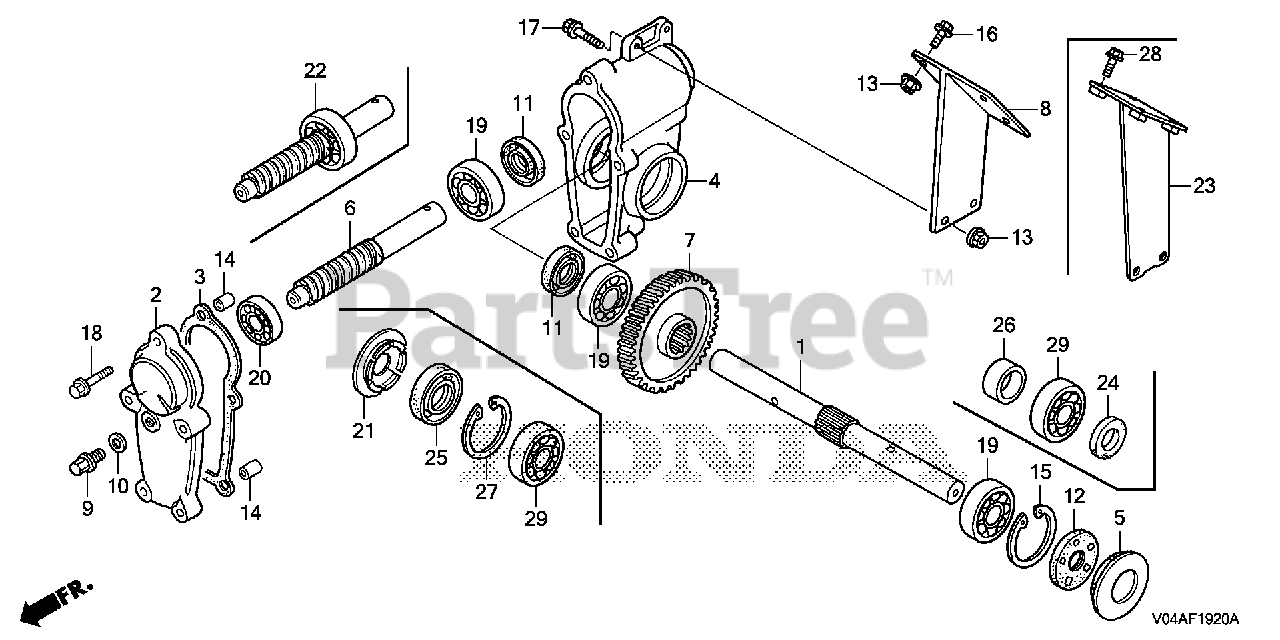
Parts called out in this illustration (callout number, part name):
1	SHAFT, AUGER
2	COVER, AUGER TRANSMISSION
3	GASKET, AUGER TRANSMISSION
4	CASE, AUGER TRANSMISSION
5	CAP, AUGER CASE
6	GEAR, DRIVE
7	GEAR, DRIVEN (55T)
8	BRACKET, AUGER HOUSING
9	BOLT, DRAIN PLUG
10	WASHER, DRAIN PLUG (10.2MM)
11	OIL SEAL (20X32X7)
12	OIL SEAL (20X42X8)
13	NUT, FLANGE (8MM)
14	PIN, DOWEL (8X14)
15	CIRCLIP (INNER) (42MM)
16	BOLT, FLANGE (8X14)
17	BOLT, FLANGE (8X25)
18	BOLT, FLANGE (6X32)
19	BEARING, RADIAL BALL (6004)
20	BEARING, RADIAL BALL (6202)
